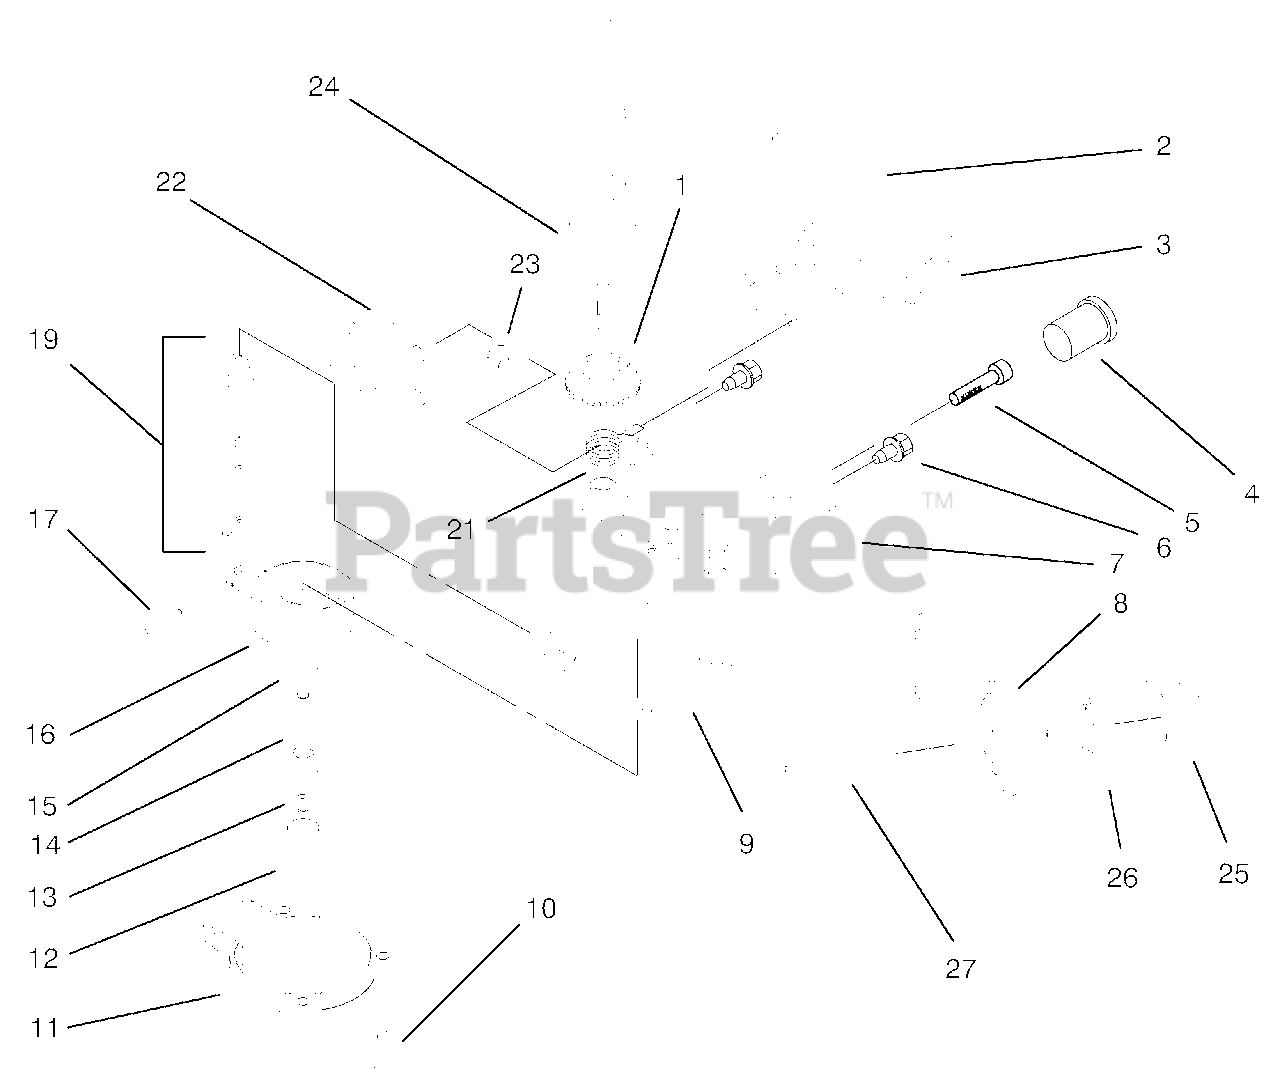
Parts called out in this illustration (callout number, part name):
1	Collar-Adjustment
2	Retainer
3	Lever-Speed Adjust
4	Plug
5	Screw-Pan Hd. Sems
7	Body-Carburetor
8	Bracket-Primer
9	Gasket-Float Chamber
11	Float Chamber
12	Filter-Fuel
13	Main Jet
16	Float & Arm Assembly
19	Float, Valve, & Body Ass'y
21	Spring-Governor
22	Bracket-Throttle Control
23	Disc-Throttle
24	Air Vane & Shaft
25	Bulb-Primer
26	Body-Primer
27	Hose-Primer
